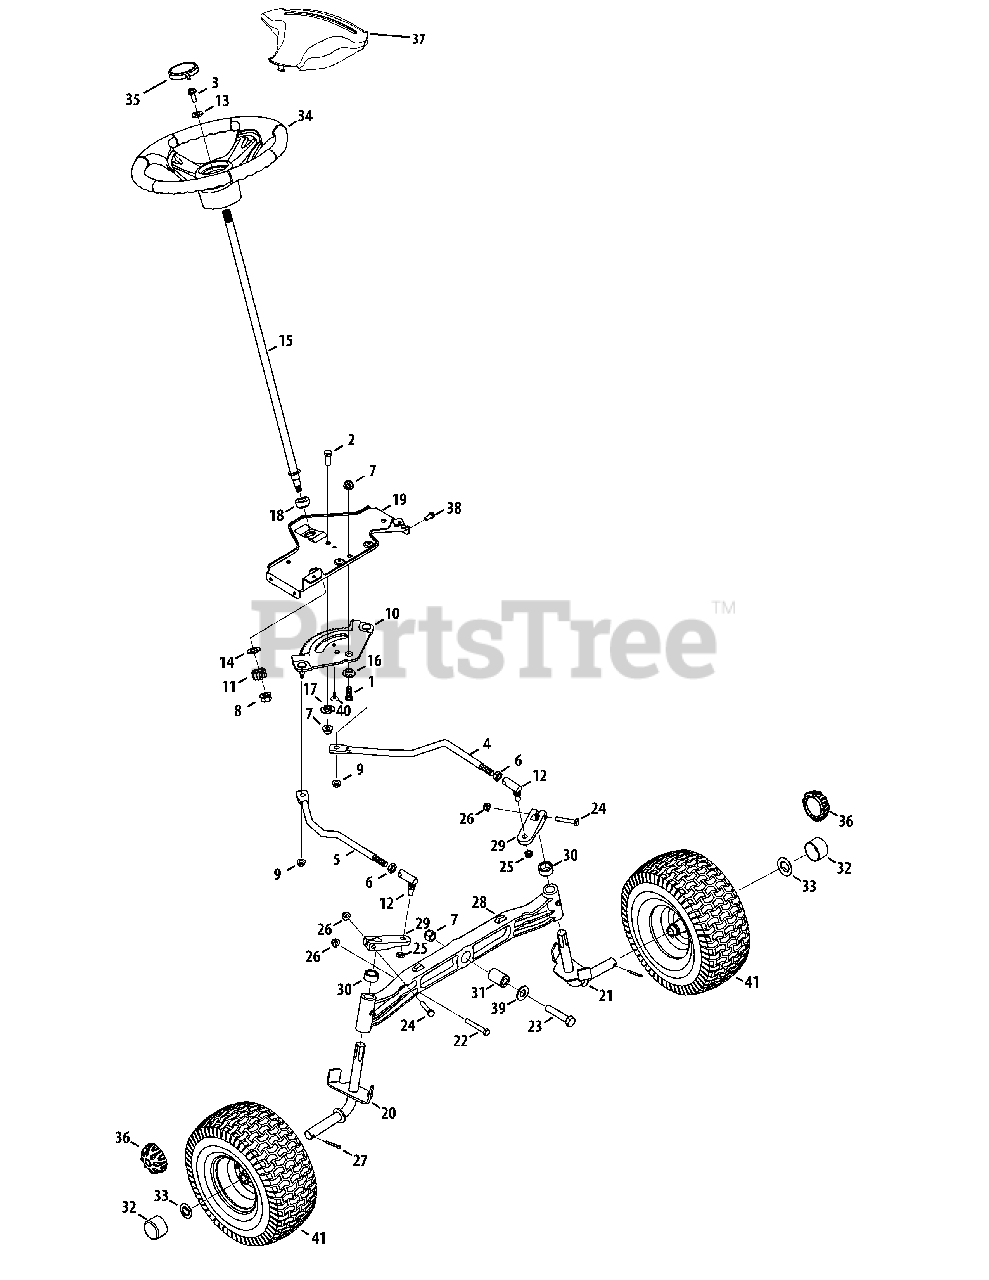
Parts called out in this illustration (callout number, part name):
1	Screw, 3/8-16 x 1.0
2	Hex Screw 3/16 x 1.00
3	Hex Screw 5/16-18 x 1.00 Special
4	Link, Drag LH
5	Link, Drag RH
6	Hex Jam Nut 7/16-20
7	Flange Lock-Nut 3/8-16 Gr. F Nylon
8	Flange Lock Nut, 7/16-20
9	Hex Flange L-Nut 5/16-18
10	Steering Gear, 11/90 Ratio
11	Steering Pinion Gear
12	Ball Joint, 7/16 - 20
13	Flat Washer .406 ID x .875 DE x .105
14	Flat Washer .510 x 1.120 x .060
15	Steering Shaft .625 OD x 24.25
16	Shoulder Spacer .385 x 1.25 x .3025
17	Spacer .38 x 1.375 Special
18	Hex Flange Bearing 5/8
19	Steering Support Bracket
20	Axle Ass’y RH .750 Dia. (46" Deck)
20	Axle Ass’y RH .750 Dia. (42" Deck)
21	Axle Ass’y LH .750 Dia. (46" Deck)
21	Axle Ass’y LH .750 Dia. (42" Deck)
22	Hex Bolt 5/16-18 x 2.25
23	Hex Cap Screw, 3/8-16 x 2.5
24	Hex Screw 5/16-18 x 1.75" Lg.
25	Hex Cent L-Nut 3/8-24
26	Flange Locknut 5/16-18 Gr. F, Ny lon
27	Cotter Pin 5/32" Dia.
28	Pivot Bar (cast)
29	Steering Block
30	Spacer .710 ID x .125 OD x .56
31	Spacer .385 x 1.0 x 1.5075
32	Hub Cap
33	Flat Washer .350 x 1.559 x .062
34	Steering Wheel, Standard Grip
34	Steering Wheel, Softgrip
35	Steering Wheel Cap (sprig) logo
36	Hub Cap
37	Steering Wheel Cover (w/o sprigs)
38	S-Tapp Scr. 5/16-18 x .75
39	Flat Washer .406 x .875 x .059
40	Rachet Clip
41	See Front & Rear Wheel Chart
